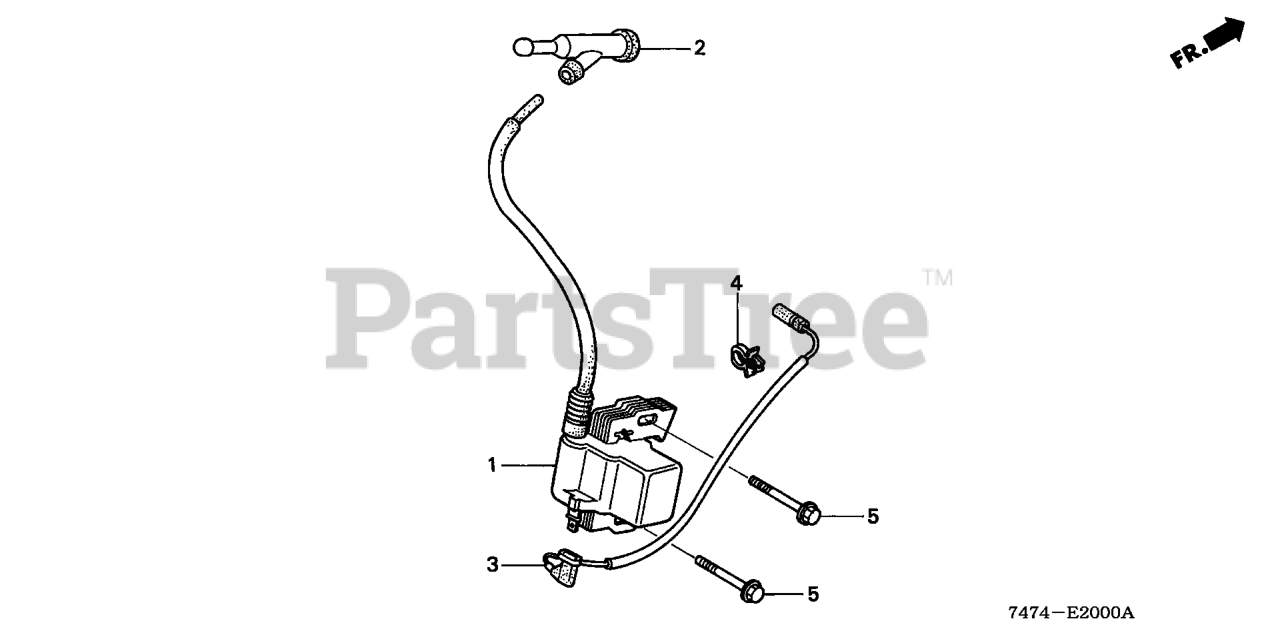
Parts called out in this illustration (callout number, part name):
1	COIL ASSY., IGNITION Use up to Engine SN 1530314.
2	CAP ASSY., NOISE SUPPRESSOR (Honda Code 3526837). (NICHIWA Y-EZ RTFM256)
3	WIRE, STOP SWITCH (230MM)
5	BOLT, FLANGE (6X25) Use up to Engine SN 2056819.
